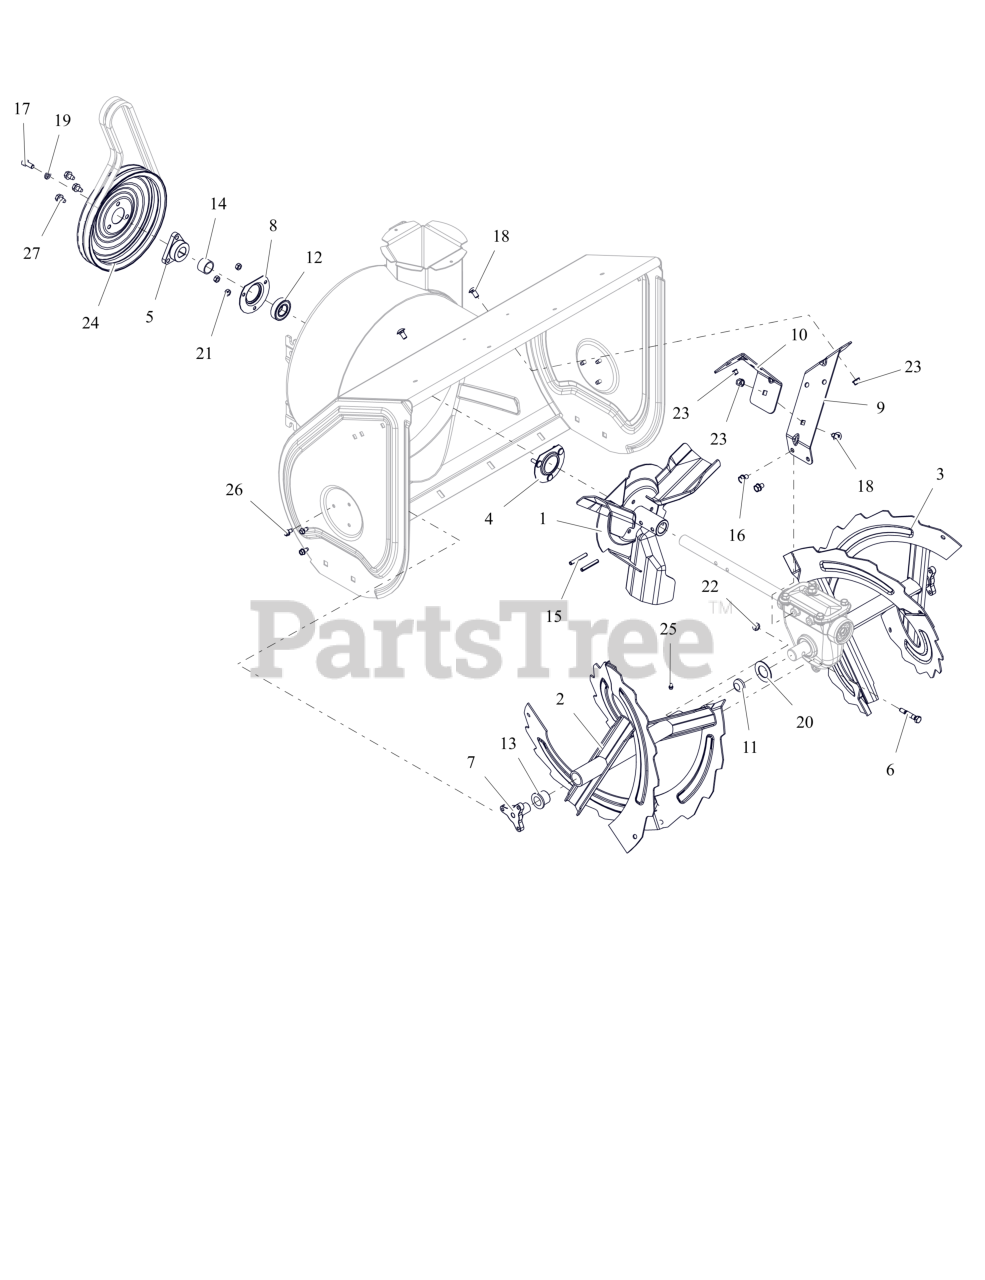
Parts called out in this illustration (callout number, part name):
1	IMPELLER, 3 BLADE-14"
2	RAKE, RH W/ZERK - 28"
3	RAKE, LH W/ZERK - 28"
4	BEARING FLANGE
5	PULLEY HUB, D-BORE .87 PRO
6	SHEAR BOLT SERVICE ASSEMBLY
7	SUPPORT, RAKE BUSHING
8	BEARING FLANGE
9	BRACKET, GEARCASE SUPPORT - LH
10	BRACKET, GEARCASE SUPPORT - RH
11	PLUG, RAKE TUBE
12	BRG-BALL .876X1.75X.50 RSTFP
13	BSHG-FLG, NY.778 ID X 1.018 OD
14	BSHG,SPCR .895X1.065X.693
15	PIN-ROLL .250X1.75
16	BLT, SEMS .31-18X.50 G5 ZCC
17	BLT, HEX .31-24X.750 G5 ZCC
18	BLT,RHSSN.31-18X.625 G5 ZCCP30
19	WSHR, LK-HVY .312X.097 ZCC
20	WSHR- FLT 1.010X1.755X.062 ZCC
21	NUT,LK-CTR .25-20 GA ZCC
22	NUT,LK-CTR .31-18 GA ZCC
23	NUT-LK-TOP-FLG .312-18 GF ZCC
24	PULLEY, SPIN FORM DUAL GROOVE
25	ZERK,FITTING .25X.125 DRIVE IN
26	SCR-TAP .25-20X.50 HWH ZCC
27	SCR,TAP .312-18X.50 HWH TR ZCC
